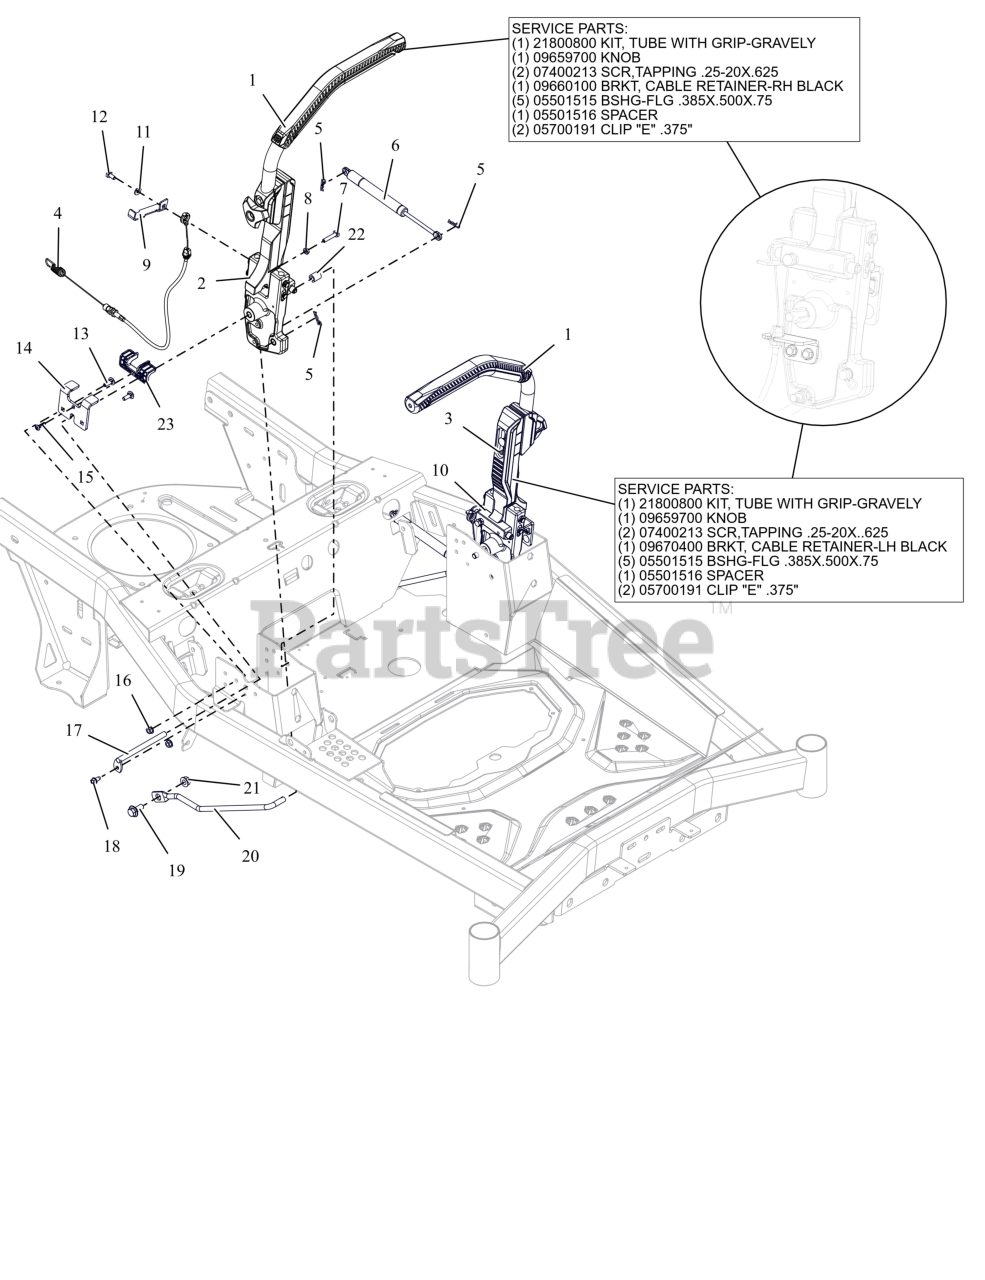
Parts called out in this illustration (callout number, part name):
1	ASM-HANDLE BAR -GRAVELY
1	KIT- ARMRESTS (CUSTOM PAD)
1	KNOB- STEERING ADJUSTMENT
1	SELF TAPPING SCREW, .25-20X.625
1	BRKT- CABLE RETAINER
1	BSHG-FLG .385X.500X.75
1	SPACER SLEEVED .385X.500X1.045
1	3/8" E RETAINING RING EXTERNAL
2	ASM- CONTROLS LWR -RH GRAVELY
3	ASM- CONTROLS LWR -LH GRAVELY
4	CABLE- PARK BRAKE
5	PIN, HAIR #213 .08X1.19 ZCC
6	DAMPER- STRAIGHT MOUNT
7	BLT, HEX 0.25-20X1.25F GR5 ZCC
8	NUT-JAM .250-20 G2 ZCC
9	BRKT, PARKING BRK ENG R (BLACK)
10	BRKT, PARKING BRK ENG L (BLACK)
11	WSHR,FLT .281X.625X.065 ZCC
12	BLT, HEX 0.375-16X1 GR5 EP80 ZC120
13	BLT, RHSN .25-20X.750 G5 ZCC
14	PLATE- BRAKE STOP
15	SCR-TAP 12-14X.75PLSTITE @BLZC
16	NUT-LK-CTR-FLG .25-20 ZC120
17	PIN- FIXED STEERING PIVOT
18	SCR-TAP .25-20X.50 HWH ZCC
19	BLT- SHLDR .375-16X.100X.72
20	WIREFORM- STEERING LINKAGE
21	NUT-LK-CTR-FLG .375-16 GF ZCC
22	SPCR- SNAP-ON 1/2 X 1 1/2
23	STEERING, PLASTIC LINER
